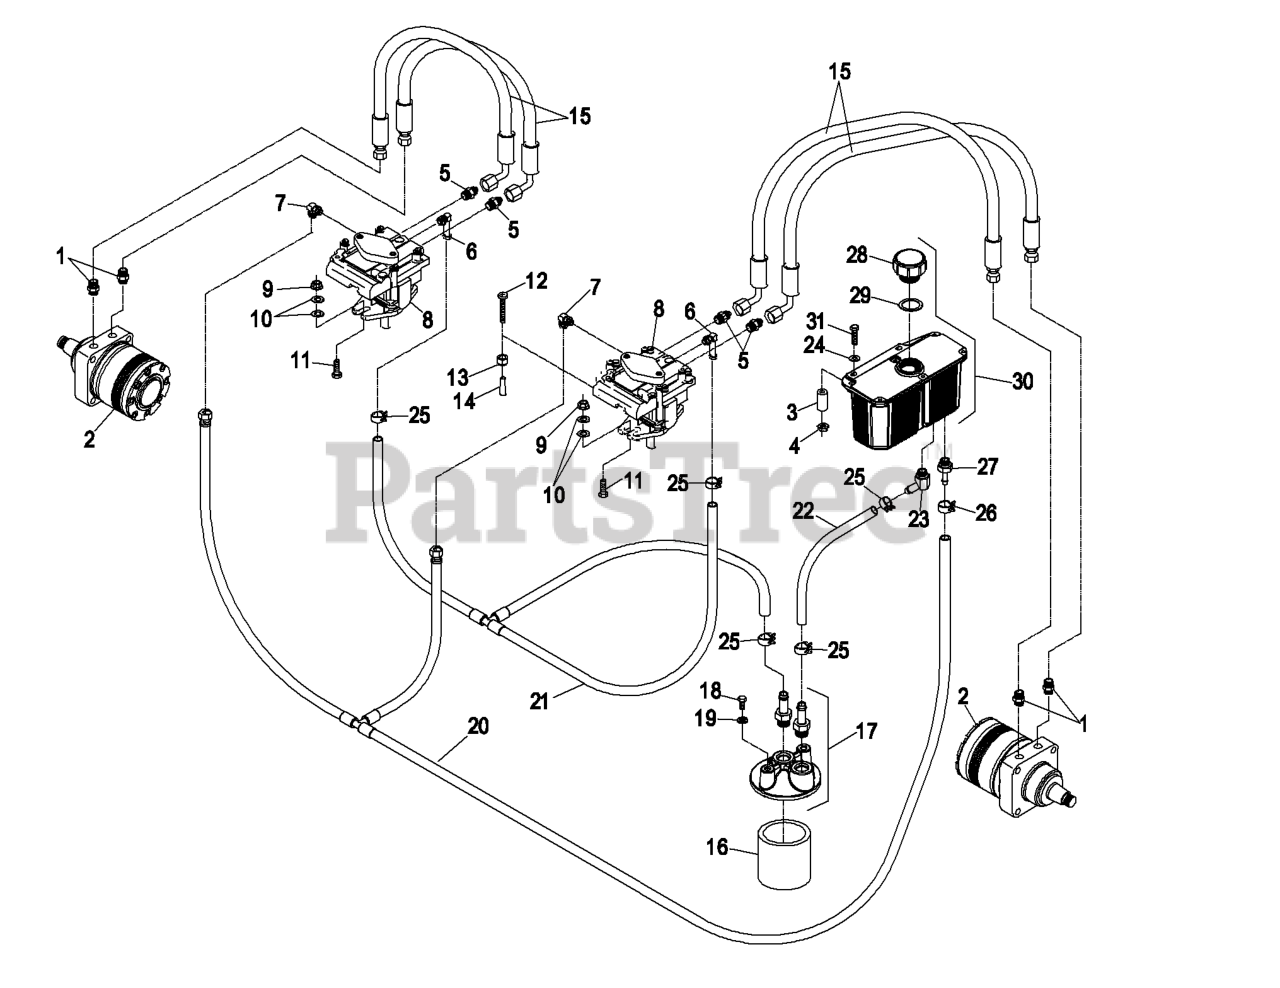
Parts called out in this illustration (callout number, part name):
1	FITTING-STRAIGHT
2	HYD MOTOR ASM
5	FITTING-STRAIGHT
6	FITTING
7	FITTING-90 DEG
9	NUT-HHF, WHIZ
10	WASHER-FLAT
11	SCREW-HH
13	NUT-LOCK, NI
14	GRIP-VALVE, DUMP
17	FILTER HEAD ASM
18	SCREW-HH
19	WASHER-LOCK
20	HYD HOSE ASM
21	HYD HOSE ASM
22	HOSE-CHARGE
23	FITTING-BARBED, 45 DEG
24	WASHER-FLAT
25	CLAMP-HOSE
26	CLAMP-HOSE
27	ADAPTER-STRAIGHT
28	Cap-Reservoir, HYD
29	GASKET-CAP
30	HYD RESERVOIR ASM
31	SCREW-HH
